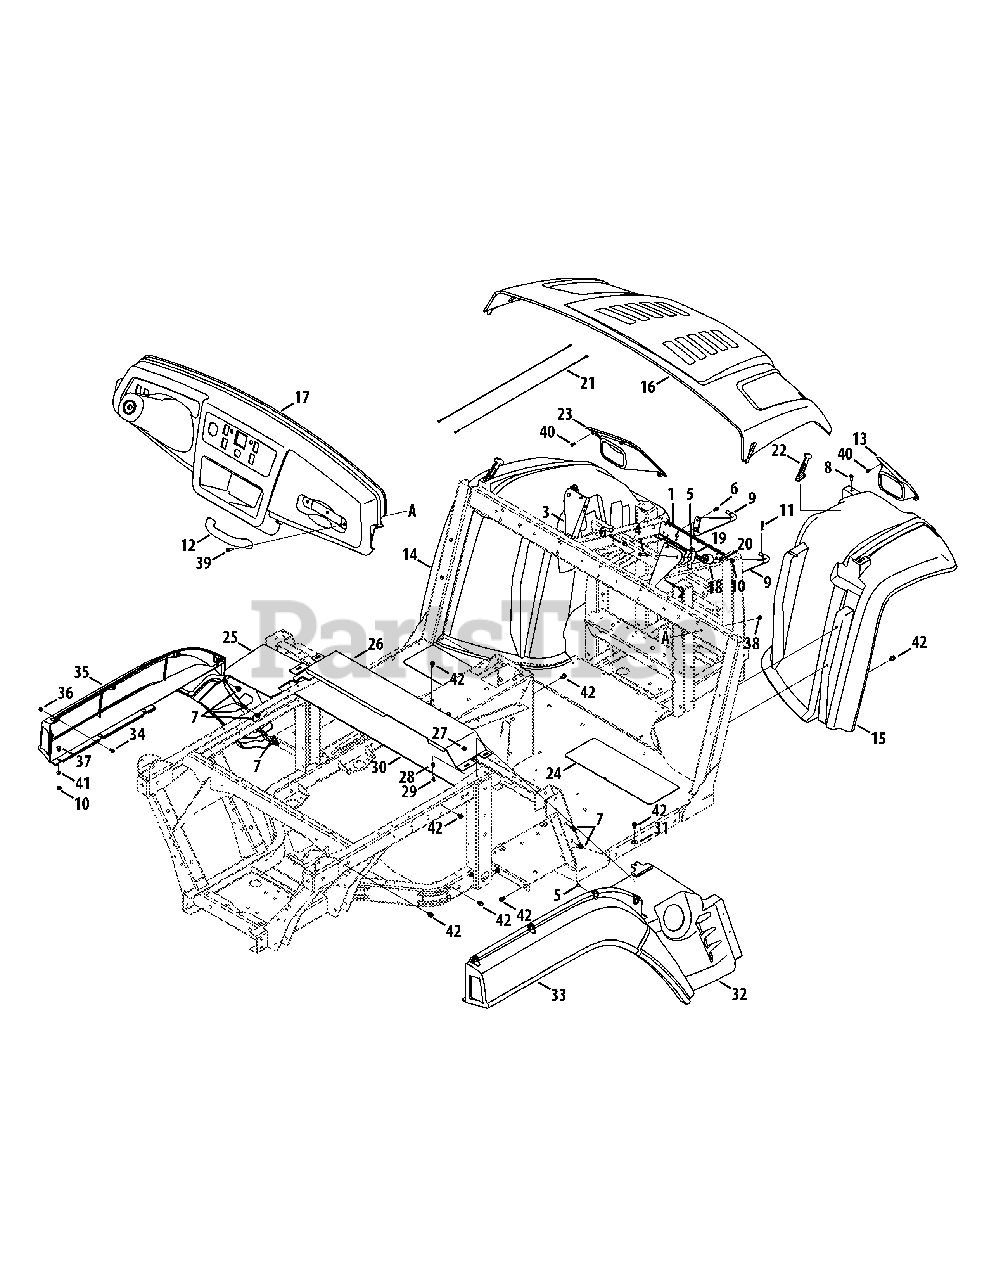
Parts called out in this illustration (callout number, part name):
1	Channel, Frame, Cross
2	Bracket, Hood/dash, Mount, RH
3	Bracket, Hood/dash, Mount, LH
4	Screw, 1/4-20, 1.75, Gr5, Std
5	Screw, #12-16 x .50
6	Screw, TT, 1/4-20 x .500
7	Screw, TT, 1/4-15 x .500
8	Hex Head Screw, 1/4-20 x 1.00
9	Rod Assembly, Hood Mount
10	Nut, Flange Lock, 1/4-20
11	Cotter Pin, Internal .08 x 1.42
12	Handle, W/Screw 400/500 S
13	Head Light RH
14	Fender, LH
14	Fender, LH , Camo
15	Fender, RH
15	Fender, RH , Camo
16	Hood, Yellow
16	Hood, Camo, Treestand
16	Hood, Green
16	Hood, Red
17	Dash, Uv
18	Roller, Latch, Hood
19	Spring, Latch, Hood
20	Washer, Flat, .283 x .75 x .030
21	Cable, Hood
22	Strap, Hood
23	Head Light LH
24	Pad, abrasive, toe plate
25	Fender, Lwr LH Rear
25	Fender, Lwr LH Rear, Camo
27	Latch, Panel, 1/4 Turn
28	Spring, Comprs, .40 OD x .040
29	Spring, Clip
30	Insulator, Cover, UV
31	Washer, Bell, .340 x .872 x .060
32	Fender, Lower RH Rear
32	Fender, Lower RH Rear Camo
33	Fender, RH Rear
33	Fender, RH Rear, Camo
34	Screw, Mach., 1/4-20 x .500
35	Fender, LH Rear
35	Fender, LH Rear, Camo
36	Nut, Acorn, 1/4-20
37	Screw, Crg, 1/4-20, .62, Gr2
38	Nut, Hex Lock., 1/4-20
39	Screw, Machine, 1/4-20 x 1.00
40	Screw, Tt, 1/4-20 x .625, Hxind.
41	Washer, Flat 1/4"
42	Screw, tt, 5/16-18 x 0.750
